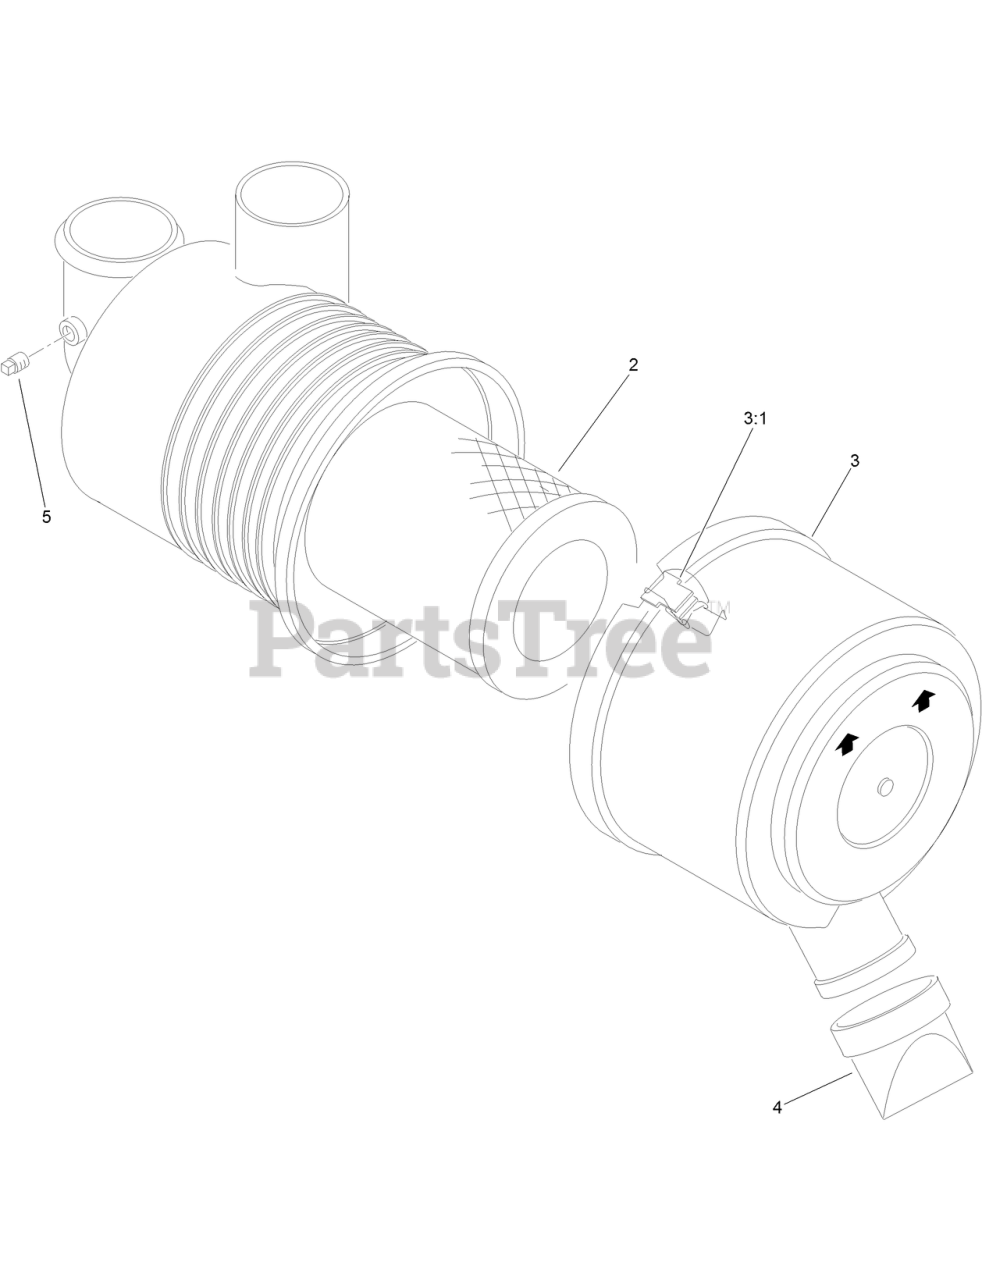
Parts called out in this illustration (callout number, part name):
2	FILTER-AIR
3	COVER ASM
3:1	LATCH-CLEANER, AIR
4	VALVE-VACUATOR
5	PLUG-PIPE
